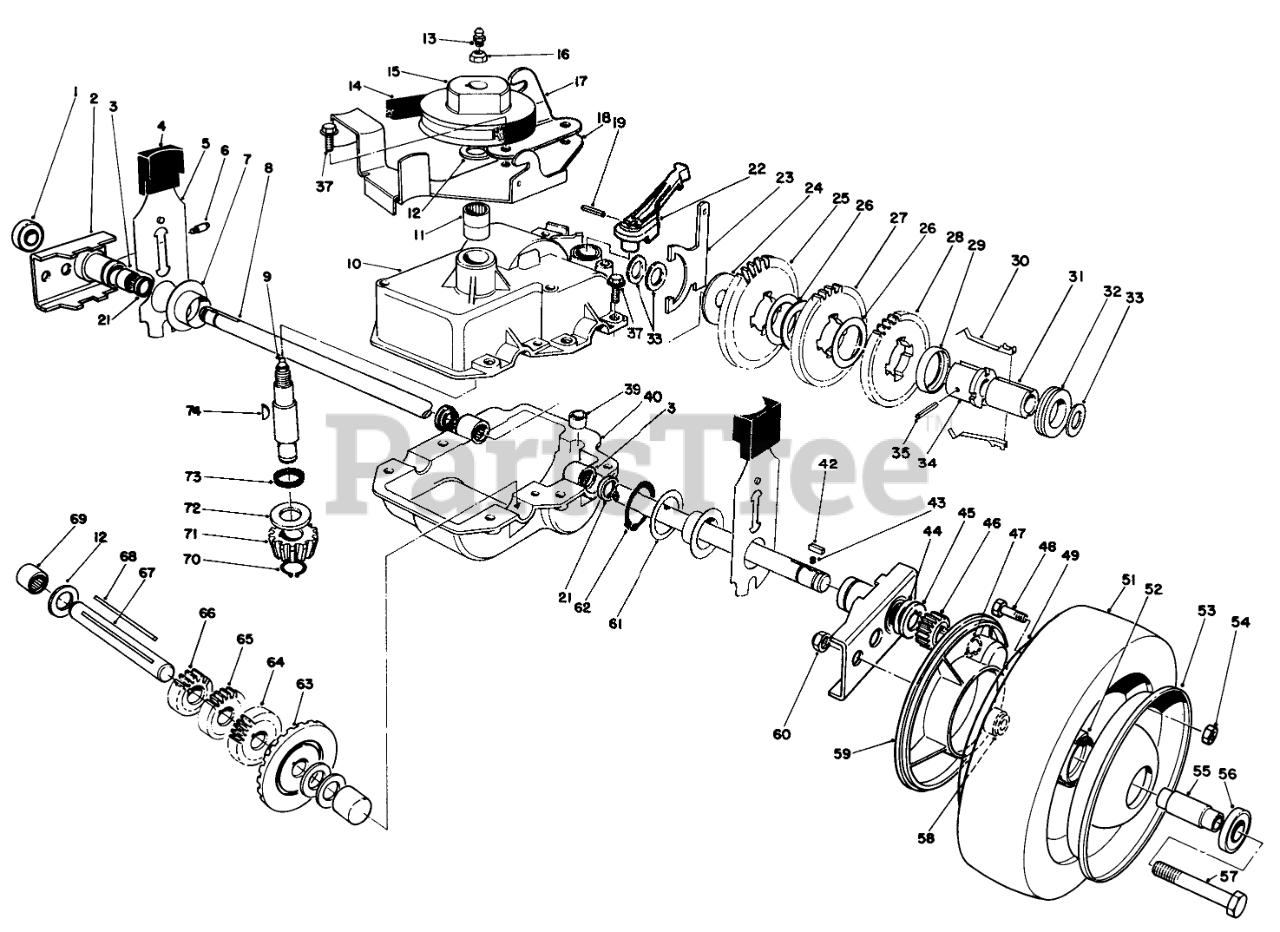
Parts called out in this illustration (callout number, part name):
1	BEARING-WHEEL
2	Pivot Arm Assembly (Incl. Ref. #1, 3, 6 & 21)
3	BEARING-ROLLER
4	KNOB-ARM
5	REAR SPRING ARM ASM
6	FITTING-GREASE
7	CAP-END
8	SHAFT-OUTPUT
9	Shaft-Input (Incl. Ref. #13)
10	Upper Case Assembly (Incl. Ref. #11 & 73)
11	BEARING-NEEDLE
12	WASHER-THRUST
13	FITTING-GREASE, ZERK
14	V-BELT
15	PULLEY
16	NUT-HEX
17	Bracket-Traction Engage
18	Belt Guide Bracket
19	PIN-COIL
21	SEAL-OIL
22	LEVER-SHIFT
23	YOKE-SHIFT
24	WASHER
26	WASHER
27	GEAR-42T
28	GEAR-38T
29	RETAINER-KEY
30	KEY-SHIFT
31	SLEEVE
32	COLLAR-SHIFT
33	WASHER-PLAIN
34	SLEEVE-GEAR
35	PIN-GROOVE
37	SCREW-HWHTF
39	BUSHING-YOKE
40	CASE-GEAR, LOWER
42	KEY RECTANGULAR
43	SPRING-COMPRESSION
44	WASHER-THRUST, OUTER
45	WASHER-THRUST, OUTER
46	GEAR-PINION
47	RING-RETAINING
48	SCREW-HH
49	Wheel-Half
52	HUB-BEARING
53	Wheel-Half
54	NUT-LOCK, NI
55	SPACER-BEARING
56	BEARING-WHEEL
57	SCREW-HH
58	SPACER-COVER, WHEEL
59	COVER-WHEEL
60	NUT-LOCK, CONE
61	WASHER
62	RING-RETAINING
63	GEAR-BEVEL
64	GEAR-18T
65	GEAR-14T
66	GEAR-12T
67	SHAFT-INTERMEDIATE
69	BEARING-NEEDLE, CLOSED
70	RING-RETAINING
71	PINION-BEVEL
72	WASHER-THRUST
74	KEY-WOODRUFF
